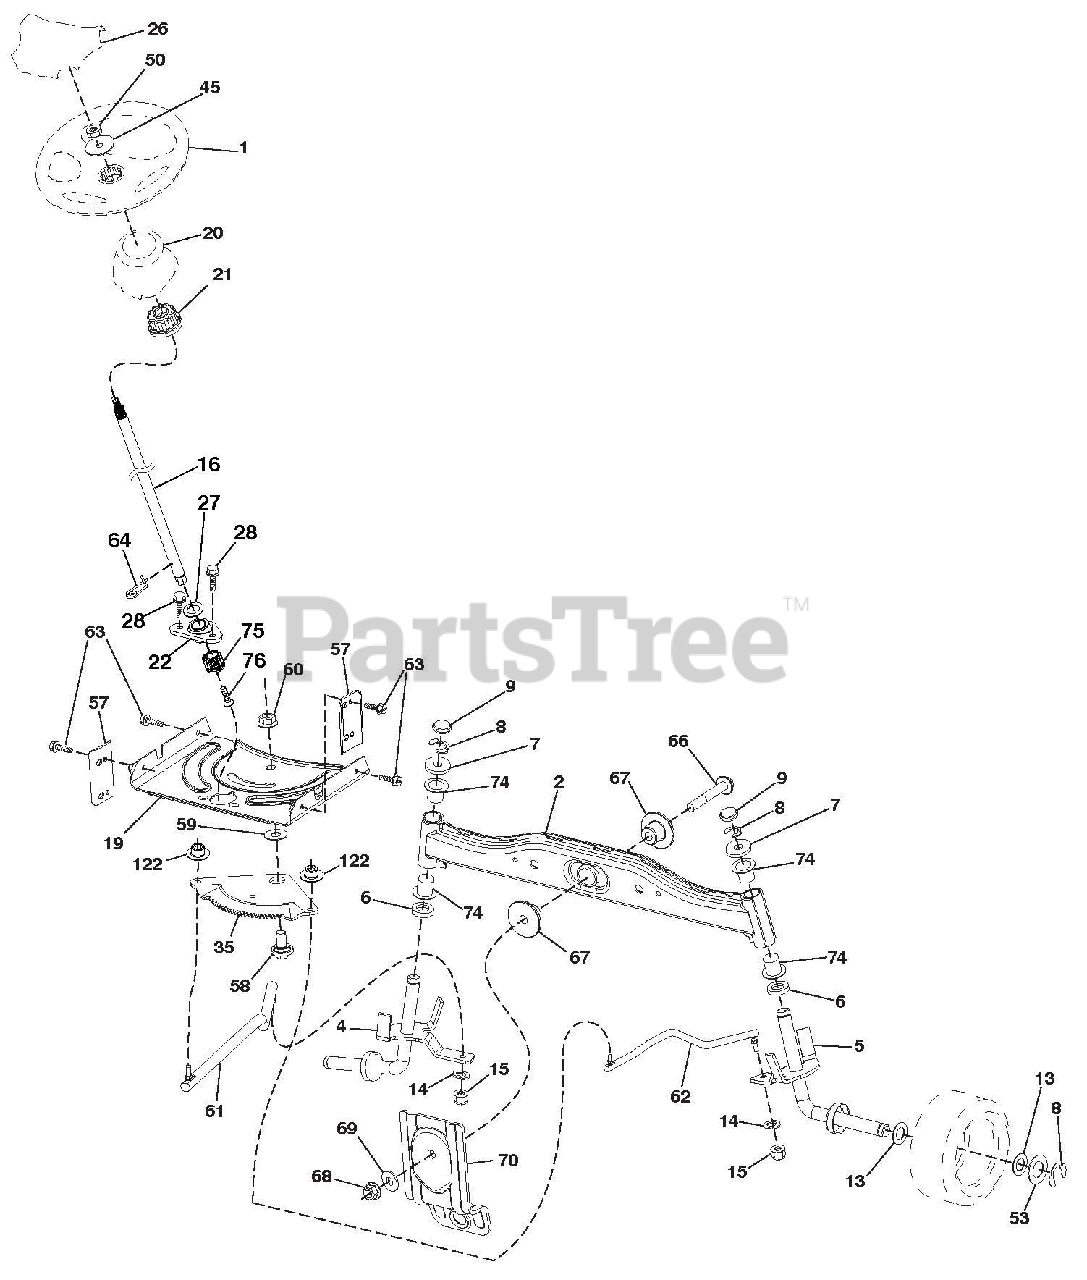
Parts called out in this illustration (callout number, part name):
1	WHEEL STEERING
2	AXLE ASM.WELDED
4	SPINDLE.WELDED.LH.15"TEX
5	SPINDLE.WELDED.RH.15"TEX
6	WAHSER THRUST .75 X 1.230
7	WASHER.25/32 X 1-5/8 X 16GA.
8	RING.KLIP.#T5304-75
9	CAP.SPINDLE.FR.TOP.BLK.
13	WASHER.25/32 X 1 1/4 X 16 GA.
14	Washer, Lock 3/8
15	NUT.CROWNLOCK.3/8-24
16	SHAFT STEER
19	PLATE.STEER.DDL.NLT/NGT
20	BOOT.STEERING
21	ADAPTER.STEER
22	STEER.SUPT. LOWER
26	CAP WHEEL STEERING HRS/SRS BLK
27	Washer 21/32 x 1 x 16 Ga.
28	SCREW.HEXWSH THDR3/8-16X3/4.BL
35	GEAR SECTOR.PLATE.DDL.NLT/NGT
50	Nut, Hex, Flangelock 3/8-16
53	WASHER.HARDEN..793 X 1.637X060
57	BRACKET.UPSTOP.TEX
58	BOLT.SHOULDER.SECTOR.PIVOT.CFM
59	WASHER.THRUST.SECTOR.STEER.NLT
60	NUT.FLANGE LOCK.5/8-11
61	DRAGLINK.LH.BALLSTUD.DDL.
62	DRAGLINK.RH.BALLSTUD.DDL
63	SCREW.5/16-18X3/4.SMGML.TAP/BL
64	RETAINER.CLIP.SPRING.STEERING
66	BOLT.HEX.FGHD.7/16-14 X 3.SERR
67	BUSHING.PM.FRONT AXLE
68	NUT.LOCK.FLANGE.7/16-14.GR5
69	WASHER.1.5 X .505 X .118
70	BRACKET
74	BEARING COL STRNG BLK
122	CAP GEAR SECTOR
